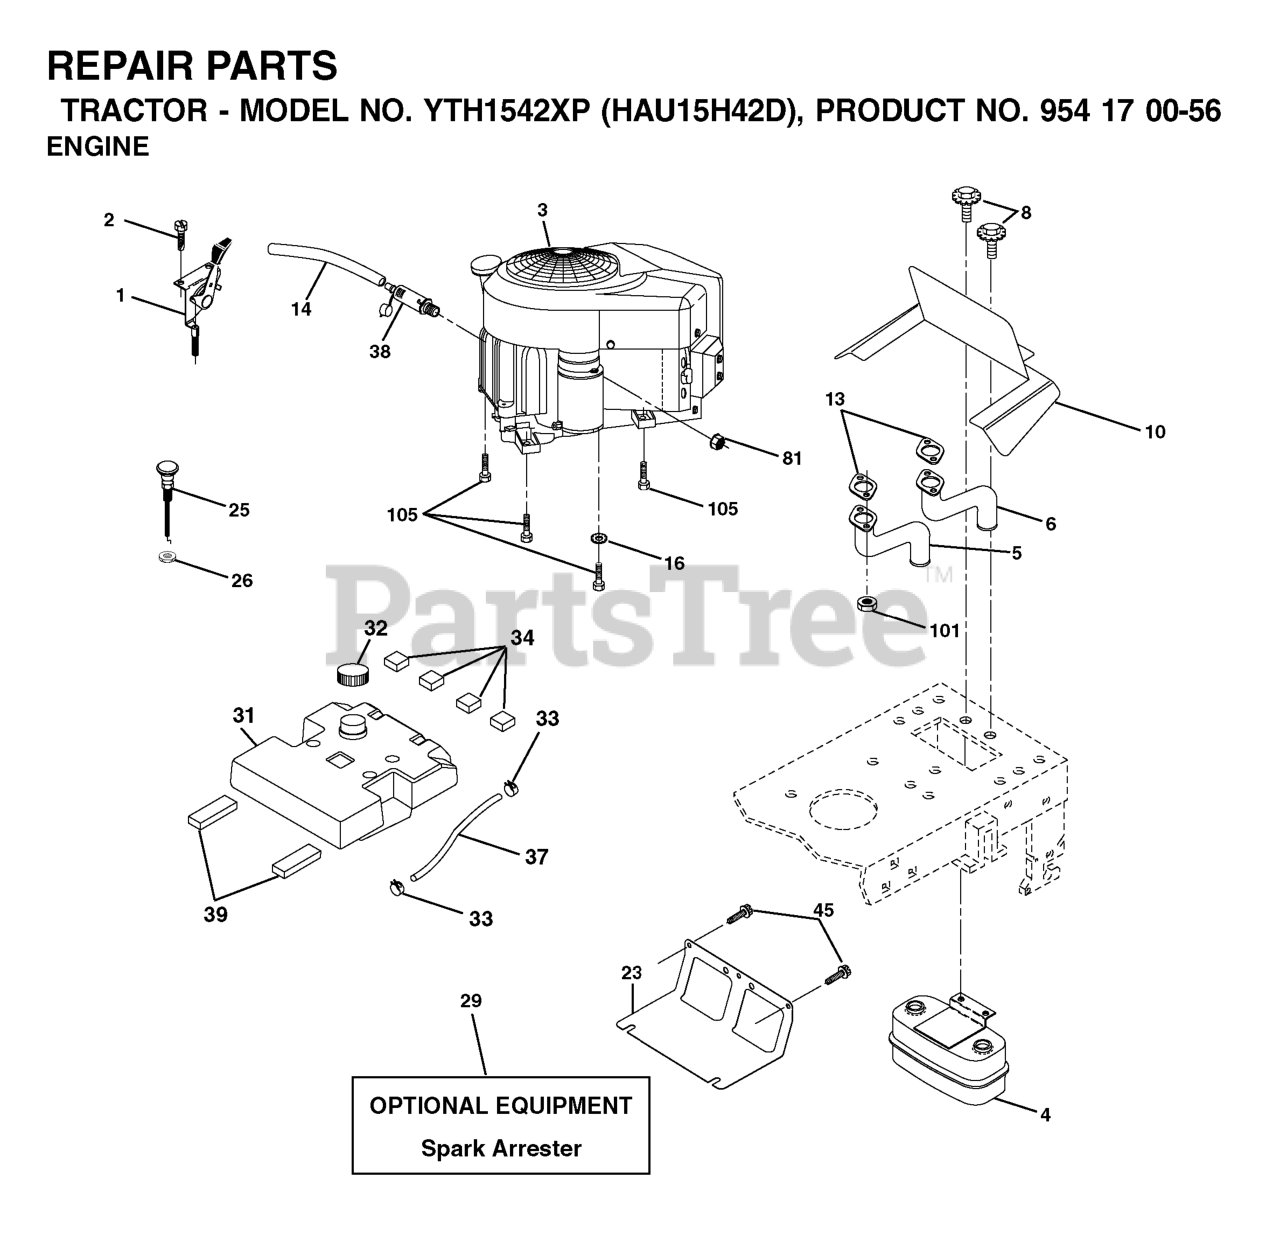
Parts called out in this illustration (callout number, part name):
1	CONTROL, THROTTLE
2	SCREW
4	MUFFLER.TWIN.CYL.LOW.TONE
5	EXHAUST TUBE LH KAWI
6	EXHAUST TUBE RH KAWI
8	BOLT.5/16-18UNCX3/4 W/SEMS.BLK
10	RP SHIELD HEAT MUFFLER
16	LOCKWASHER
23	SHIELD.BROWNING.DBR.GUARD
25	CHOKE CONTROL
26	Nut Keps 3/8 - 24 UNF
29	KIT.SPARK ARRESTOR 794945 B&S
31	TANK.FUEL(3.5.GAL)
32	FUEL CAP
33	HOSE CLAMP
34	PAD-SPACER LT
37	REPL BY 532 00 85-43
38	TUBE, DRAIN OIL ASM.
39	PAD IDLER TI
45	SCREW, 3/8-16X3/4
81	NUT
101	FLANGE NUT
105	SCREW 3/8-16X1
